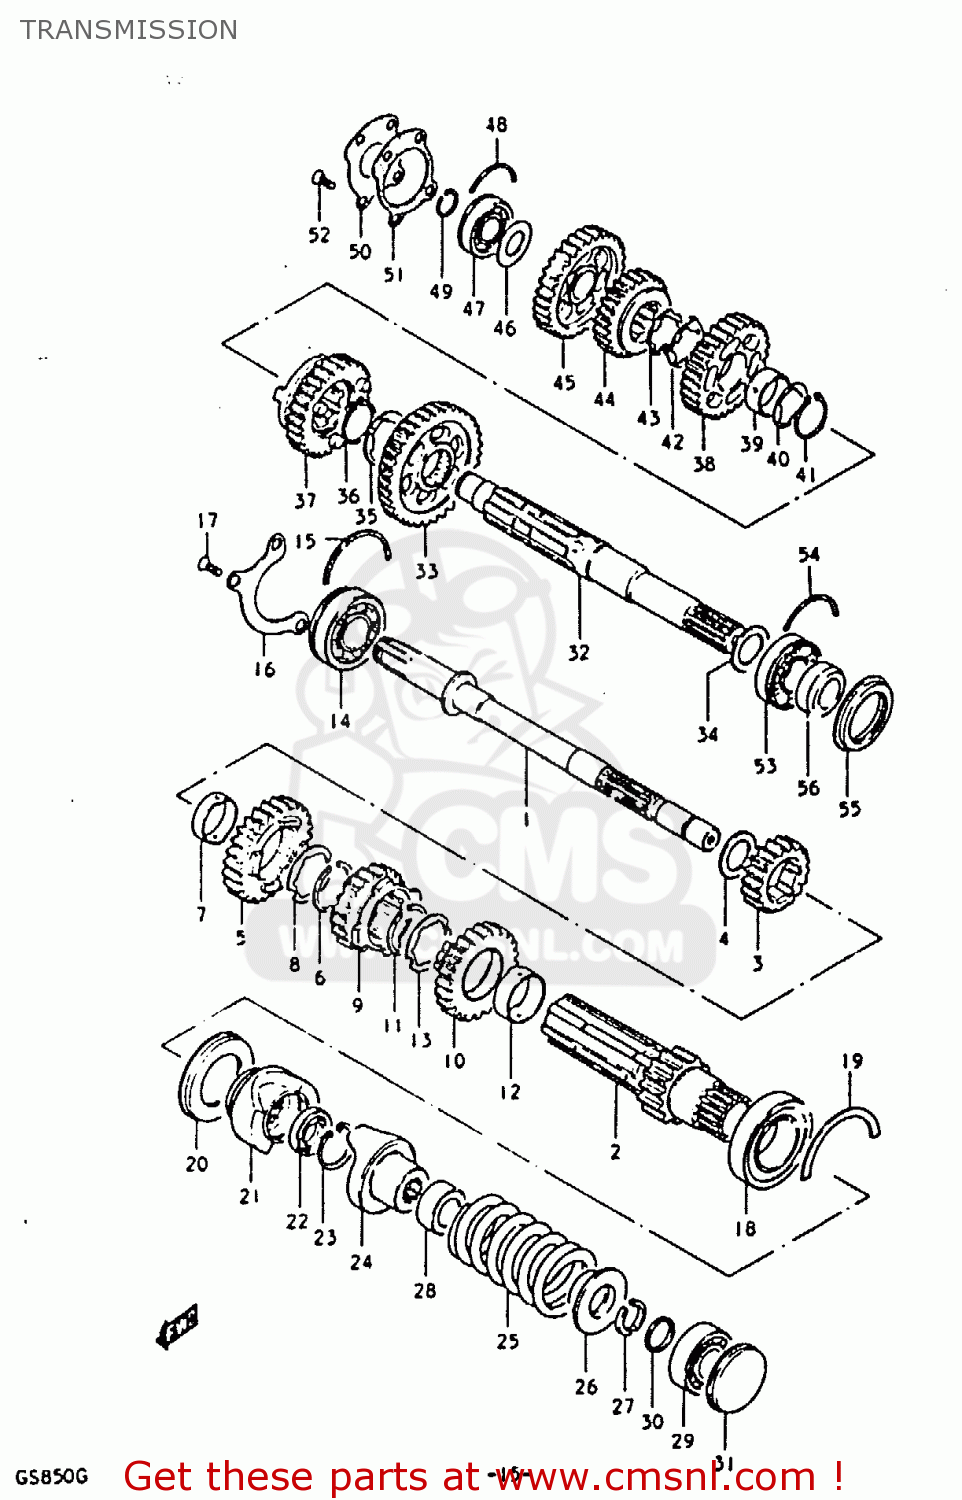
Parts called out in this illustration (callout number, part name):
1	SHAFT,COUNTER
2	SHAFT,OUTER COUNTER
3	GEAR,SECOND DRIVE
4	WASHER (21X35X2)
5	GEAR,5TH DRIVE(NT:26)
6	RING,SNAP
7	SPACER,DRIVE GEAR
8	LOCK WASHER,5TH DR GEAR SPACER
9	GEAR,THIRD DRIVE
10	GEAR,FOURTH DRIVE
11	RING,SNAP
12	SPACER,DRIVE GEAR
13	LOCK WASHER,5TH DR GEAR SPACER
14	BEARING(25X62X17)
15	C-RING
16	RETAINER,CNTR SHAFT BEARING
17	SCREW
18	BALL BEARING 32X58X13
19	C-RING
20	SEAL,OIL(40X58X7)
21	DOG,OUTPUT CAM
22	SEAL,OIL(20.6X31X6)
23	CIRCLIP
24	DOG,INPUT CAM
25	SPRING
26	STOPPER,CAM DOG
27	STOPPER,CAM DOG
28	GUIDE,CAM DOG SPRING
29	BEARING
30	SPACER (17X21X3.5)
31	PLUG
32	SHAFT,DRIVE
33	GEAR,FIRST DRIVEN
34	WASHER, LH
35	WASHER,LOCK
36	CIRCLIP
37	GEAR,FOURTH DRIVEN
38	GEAR,THIRD DRIVEN
39	BUSH,3RD DRIVEN GEAR
40	WASHER,LOCK
41	CIRCLIP
42	WASHER
43	WASHER,LOCK
44	GEAR,FIFTH DRIVEN
45	GEAR,SECOND DRIVEN
46	WASHER
47	BEARING(20X47X14)
48	C RING
49	CIRCLIP
50	PLATE,DRIVESHAFT
51	GASKET,DRIVESHAFT PLATE (MCA)
52	SCREW
53	BEARING
54	C RING
55	SEAL,OIL(35X52X6)
56	SPACER,DRIVESHAFT,LEFT
